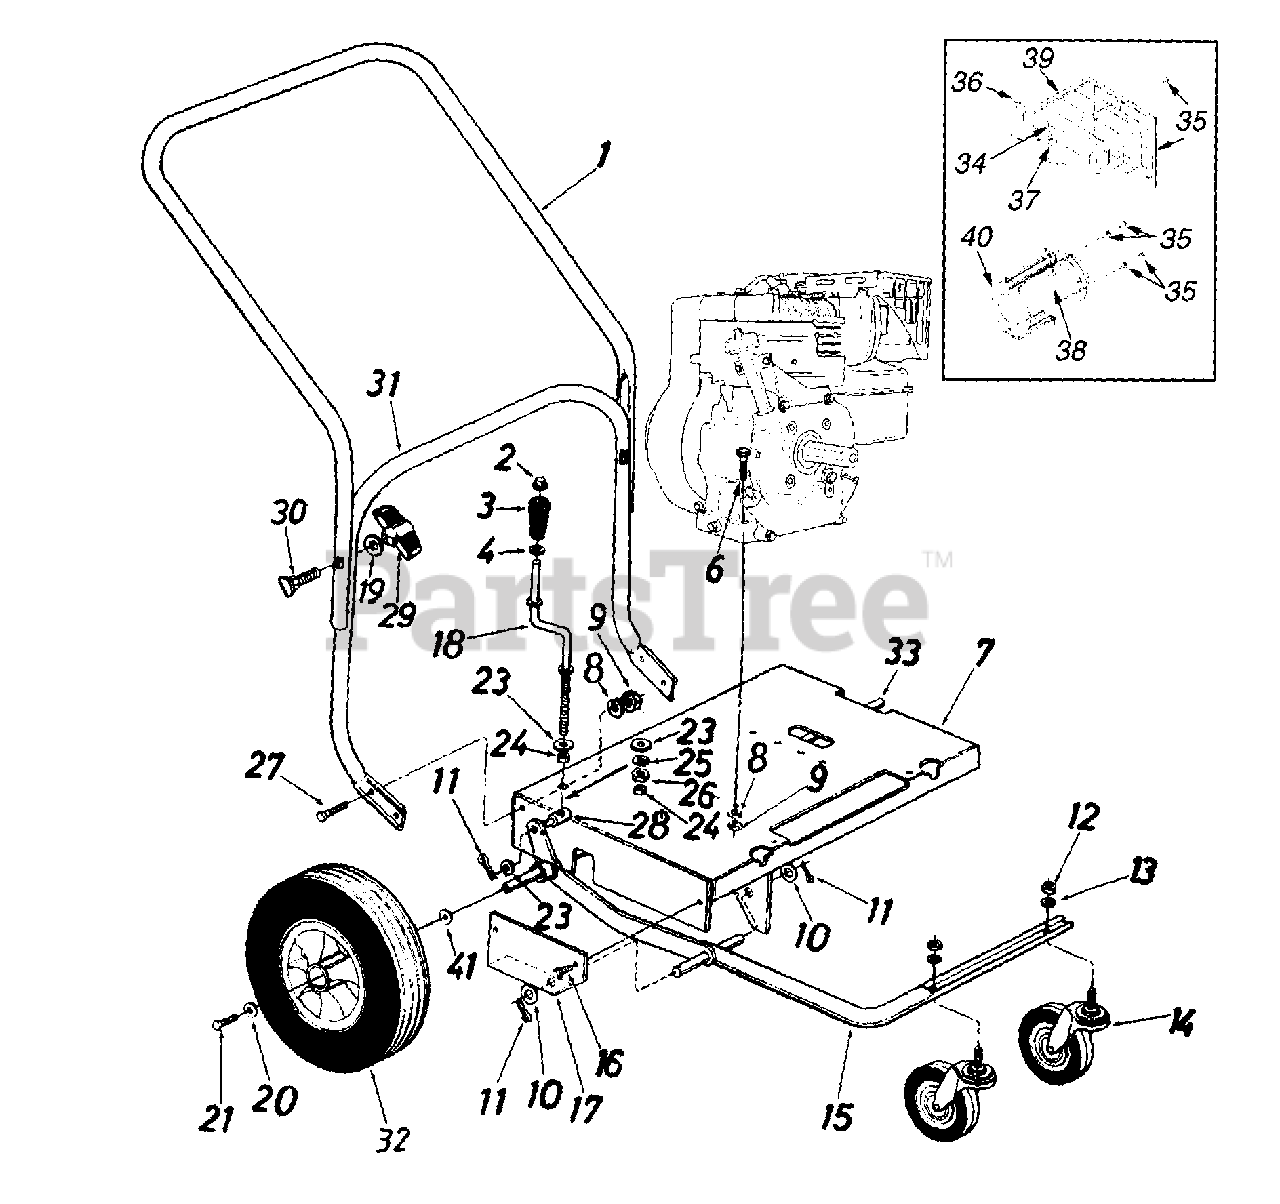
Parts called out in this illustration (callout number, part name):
2	Push Nut 3/8" Rod
3	Crank Knob
4	Fl-Wash. .385" I.D. x .62"
6	Hex Bolt 5/16-18 x 1.50" Lg.
9	Hex Nut 5/16-18 Thd.
10	Fl-Wash. .63" I.D. x 1.25"
11	Cotter Pin 1/8" Dia. x 1.0"
12	Hex Nut 1/2-13 Thd.
13	L-Wash. 1/2" I.D.
14	Swivel Caster Wheel 5" Dia. x 1.25"
19	Saddle Wash. .32" I.D. x .93"
20	Fl-Wash. .34" I.D. x .87" O.D.
21	Hex L-Bolt 5/16-24 x .64" Lg.
23	Fl-Wash. .38" I.D. x .57"
24	Spacer .382" I.D. x .50" x .180" Lg.
25	L-Wash. 3/8" I.D.
26	Hex Nut 3/8-8 Thd.
27	Hex Bolt 5/16-18 x .75" Lg.
28	Ferrule
29	Hand Knob
30	Carriage Bolt 5/16-18 x 2.0"
33	Rear Axle
34	Scr. TT. 1/4-20: .5"
35	Scr. AB 8-18:.375
36	Nut-Lock Hx. Flg. 5/16-18
37	Lockwasher
38	Deflector
39	Guard - Muffler
40	Bracket - Muffler Guard
41	Flat Washer
